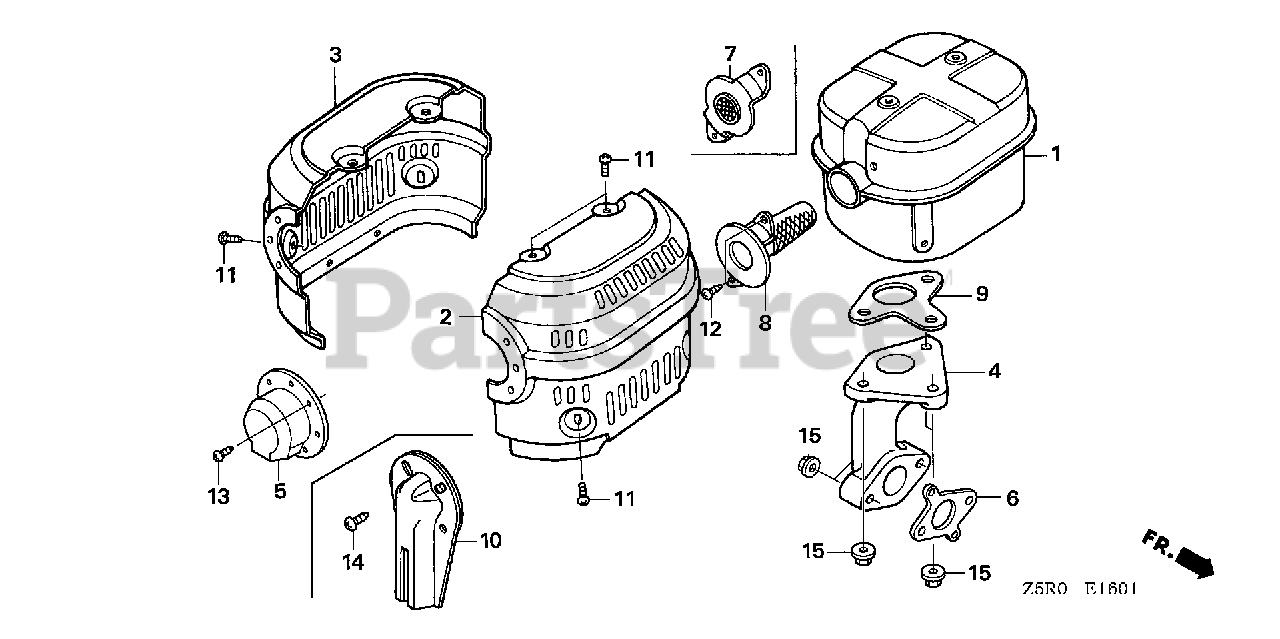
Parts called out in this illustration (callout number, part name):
2	PROTECTOR, R. MUFFLER
3	PROTECTOR, L. MUFFLER
6	GASKET, EX. PIPE
7	FLANGE, BAFFLE
9	GASKET, MUFFLER (NIPPON LEAKLESS)
11	SCREW, TAPPING (5X8)
12	SCREW, TAPPING (5X8)
15	NUT, FLANGE (8MM)
